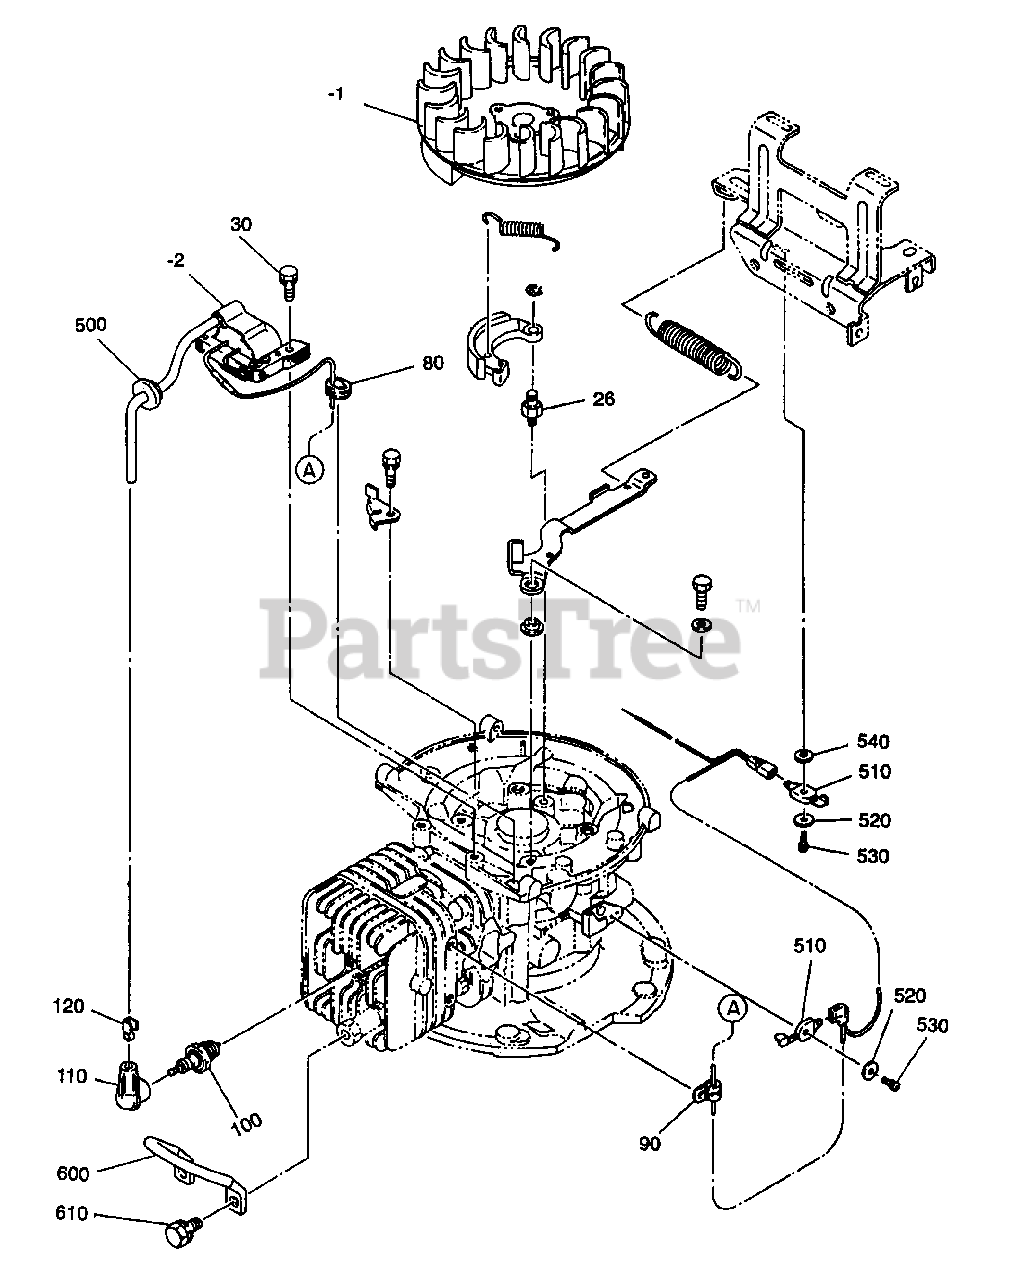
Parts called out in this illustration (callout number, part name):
1	FLY WHEEL
2	IGNITION COIL CP
26	BOLT, Pivot
30	BOLT AND WASHER ASSY
100	SPARK PLUG
110	SPARK PLUG CAP
120	PLUG TERMINAL
510	STOP SWITCH CP
530	SCREW AND WASHER ASSY
600	PLUG GUARD CP
